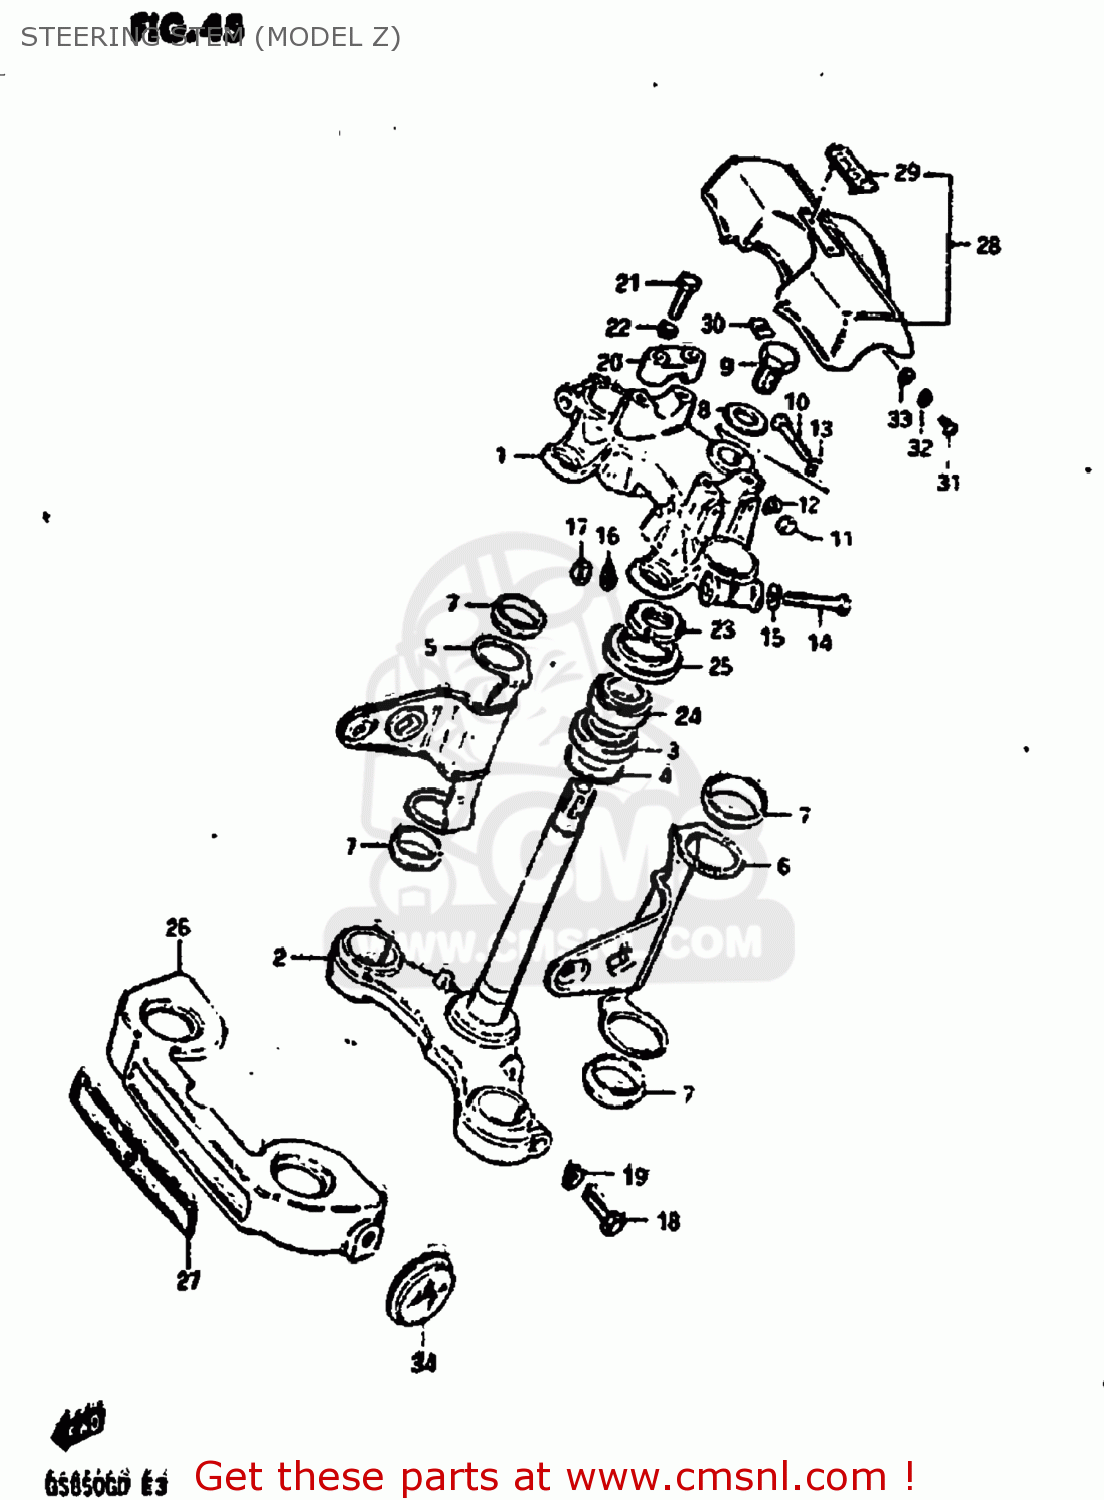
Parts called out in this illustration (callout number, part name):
1	HEAD,STEERING STEM
2	STEM,STEERING
3	BEARING
4	WASHER,THRUST
5	BRACKET,HEADLAMP,RIGHT
6	BRACKET,HEADLAMP,LEFT
7	CUSHION,HEADLAMP BRACKET
8	WASHER,STEERING STEM
9	NUT,STEM HEAD
10	BOLT 8X50
11	NUT
12	LOCK WASHER
13	WASHER
14	BOLT 10X55
15	WASHER
16	LOCK WASHER
17	NUT, LOWER LH
18	BOLT
19	LOCK WASHER
20	HOLDER,HANDLE(BLACK)
21	BOLT
22	LOCK WASHER
23	NUT,STEERING STEM
24	TAPER,ROLLER BEARING
25	DUST SEAL,STEERING UPR
26	COVER,FRONT FORK
27	EMBLEM,FRONT FORK COVER
28	PAD,HANDLEBAR
29	EMBLEM,HANDLE COVER PAD
30	NUT
31	SCREW
32	LOCK WASHER
33	WASHER
34	REFLEX REFLECTOR,RR
